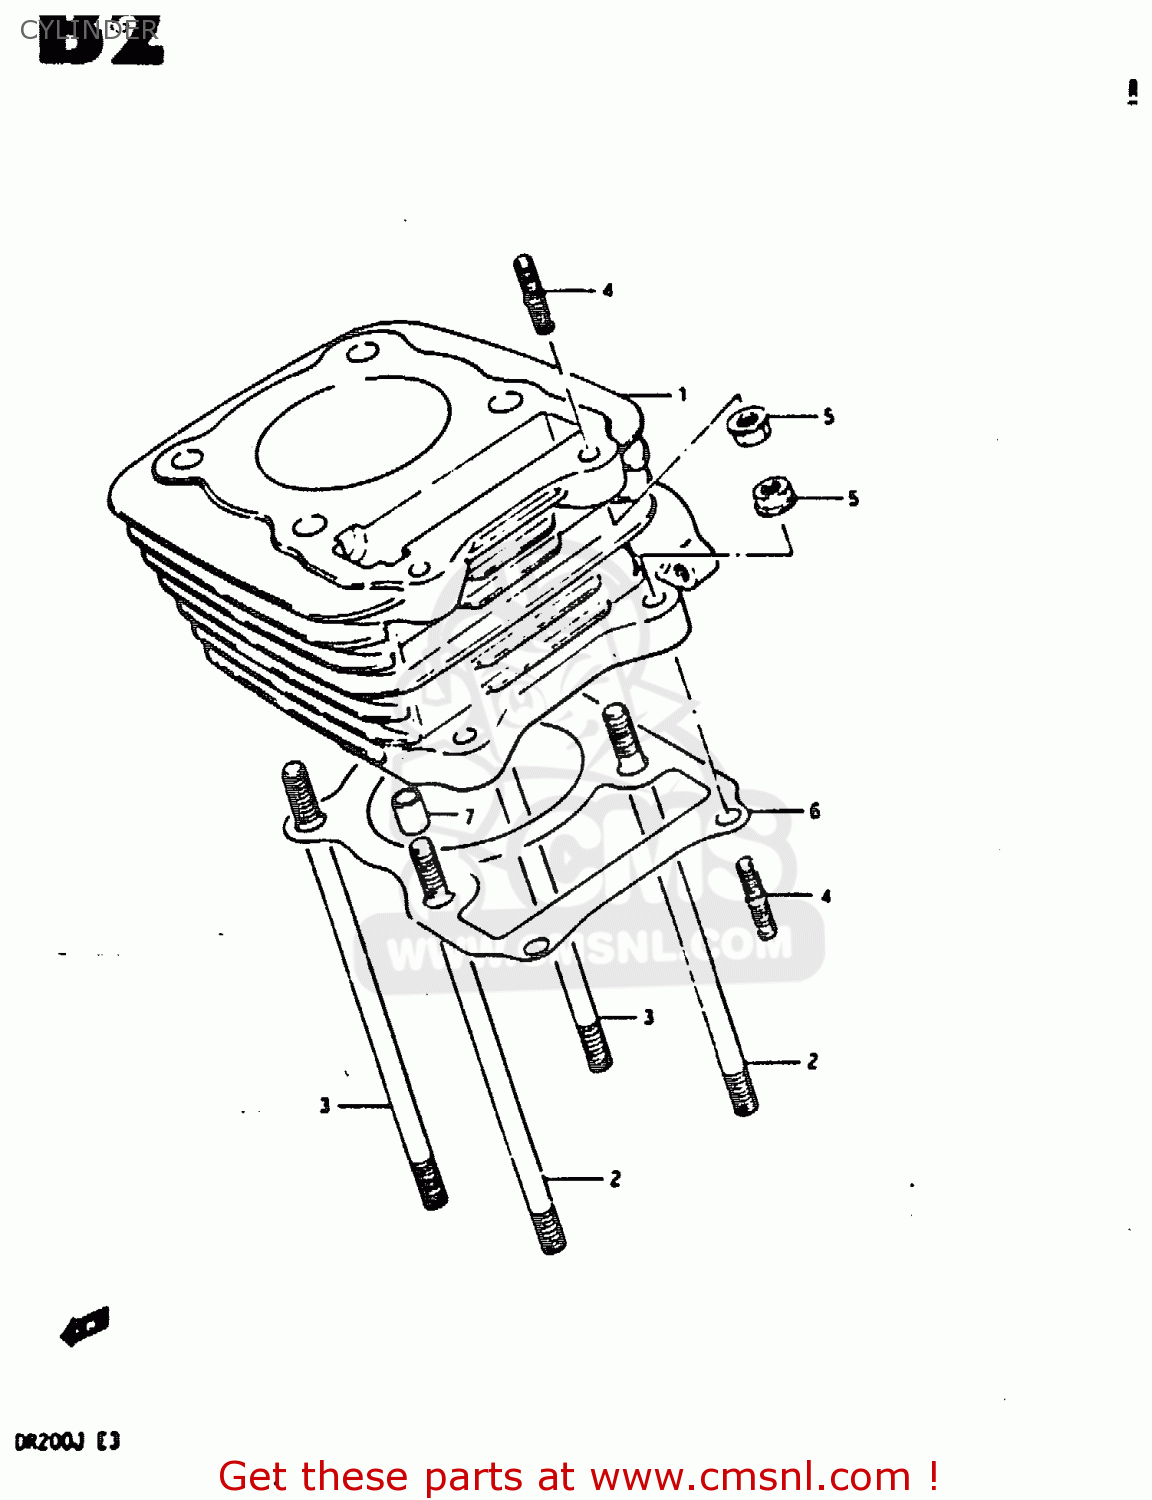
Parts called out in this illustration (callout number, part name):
1	CYLINDER
2	BOLT,STUD
3	BOLT,STUD(8X167)
4	STUD 6X25
5	NUT 6MM
6	GASKET,CYLINDER (MCA)
7	PIN
